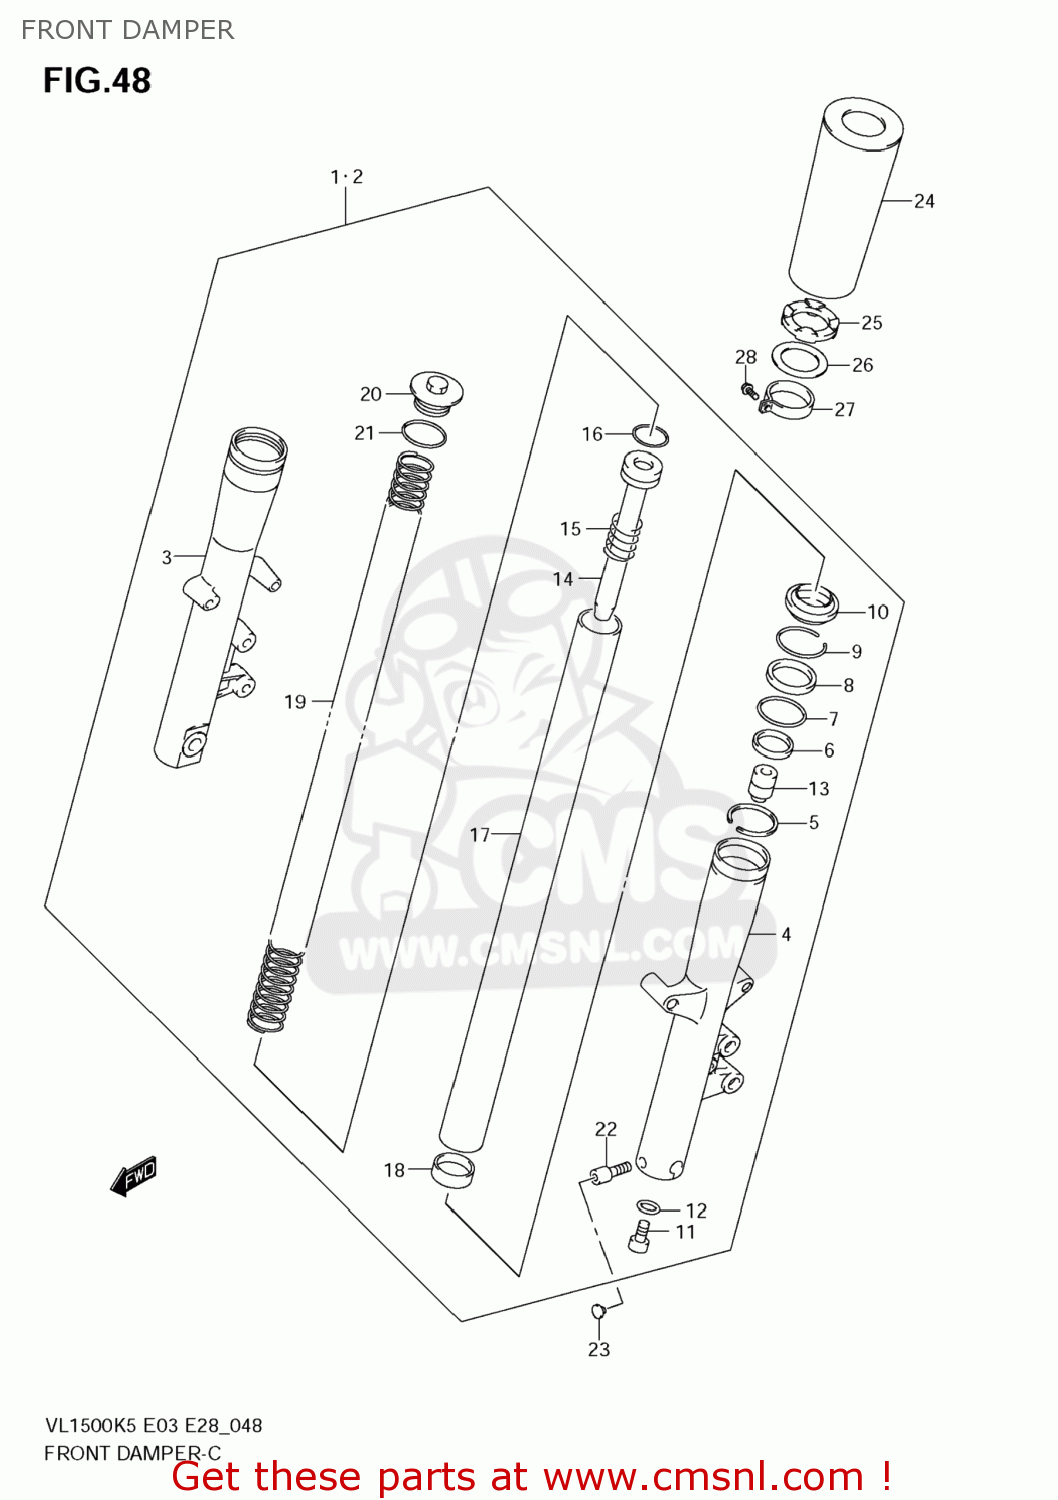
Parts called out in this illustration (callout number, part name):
1	DAMPER ASSY,FR FORK,R
2	DAMPER ASSY,FR FORK,L
3	TUBE,OUTER,R
4	TUBE,OUTER,L
5	GUIDE,CASE
6	BUSH,GUIDE
7	SPACER,SEAL
8	SEAL,OIL
9	CIRCLIP,FORK OIL SEAL
10	SEAL,DUST
11	BOLT
12	GASKET (NAS)
13	PIECE,OIL LOCK
14	SEAT,PIPE
15	SPRING,REBOUND
16	RING,PISTON
17	TUBE,INNER
18	BUSH,SLIDE
19	SPRING,FR
20	BOLT,FORK
21	O RING
22	BOLT
23	CAP(OD:14.5)
24	CASE,UNDER
25	SEAT,RUBBER
26	WASHER
27	SPACER
28	BOLT
